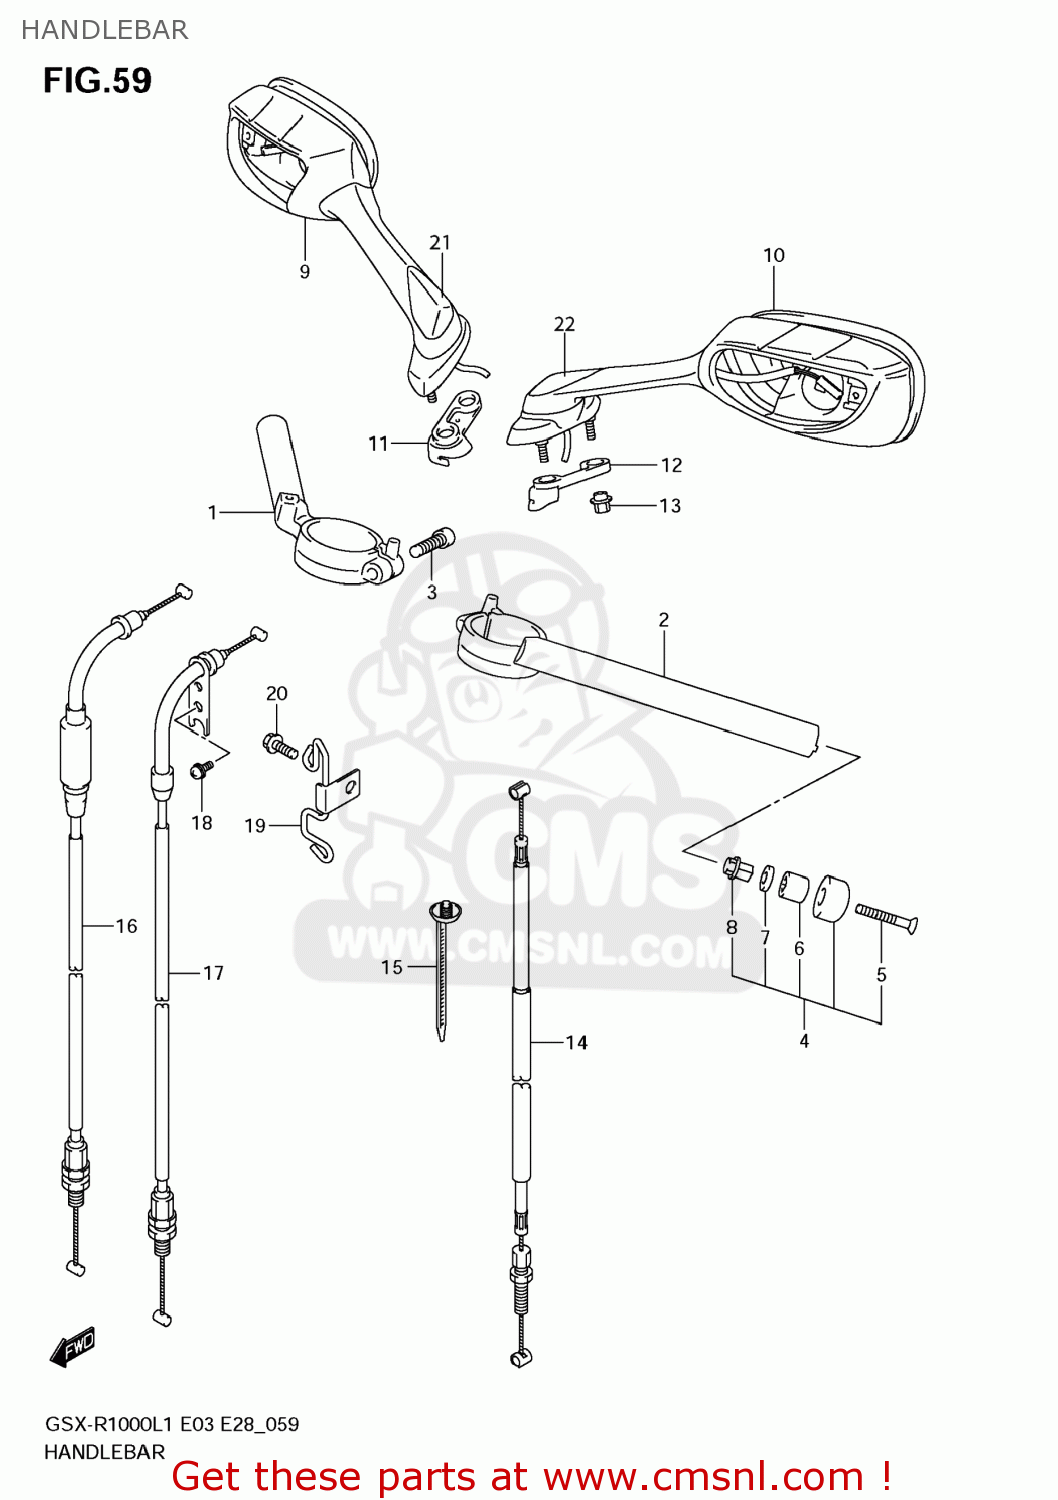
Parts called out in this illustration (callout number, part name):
1	HANDLEBAR,R
2	HANDLEBAR,L
3	BOLT(8X32)
4	BALANCER SET,HANDLEBAR
5	SCREW
6	WASHER(6.5X16X4)
7	EXPANDER,HANDLE BALANCER
8	NUT,HANDLE BALANCER
9	MIRROR ASSY,RE
10	MIRROR ASSY,RE
11	CUSHION,RR VIEW MIRRROR,R
12	CUSHION,RR VIEW MIRRROR,L
13	NUT,RR VIEW MIRROR
14	CABLE ASSY,CLUTCH
15	CLAMP(L:154)
16	CABLE ASSY,THROTTLE NO.1
17	CABLE ASSY,THROTTLE NO.2
18	SCREW(5X10)
19	GUIDE,CABLE
20	BOLT
21	CAP,R
22	CAP,L
